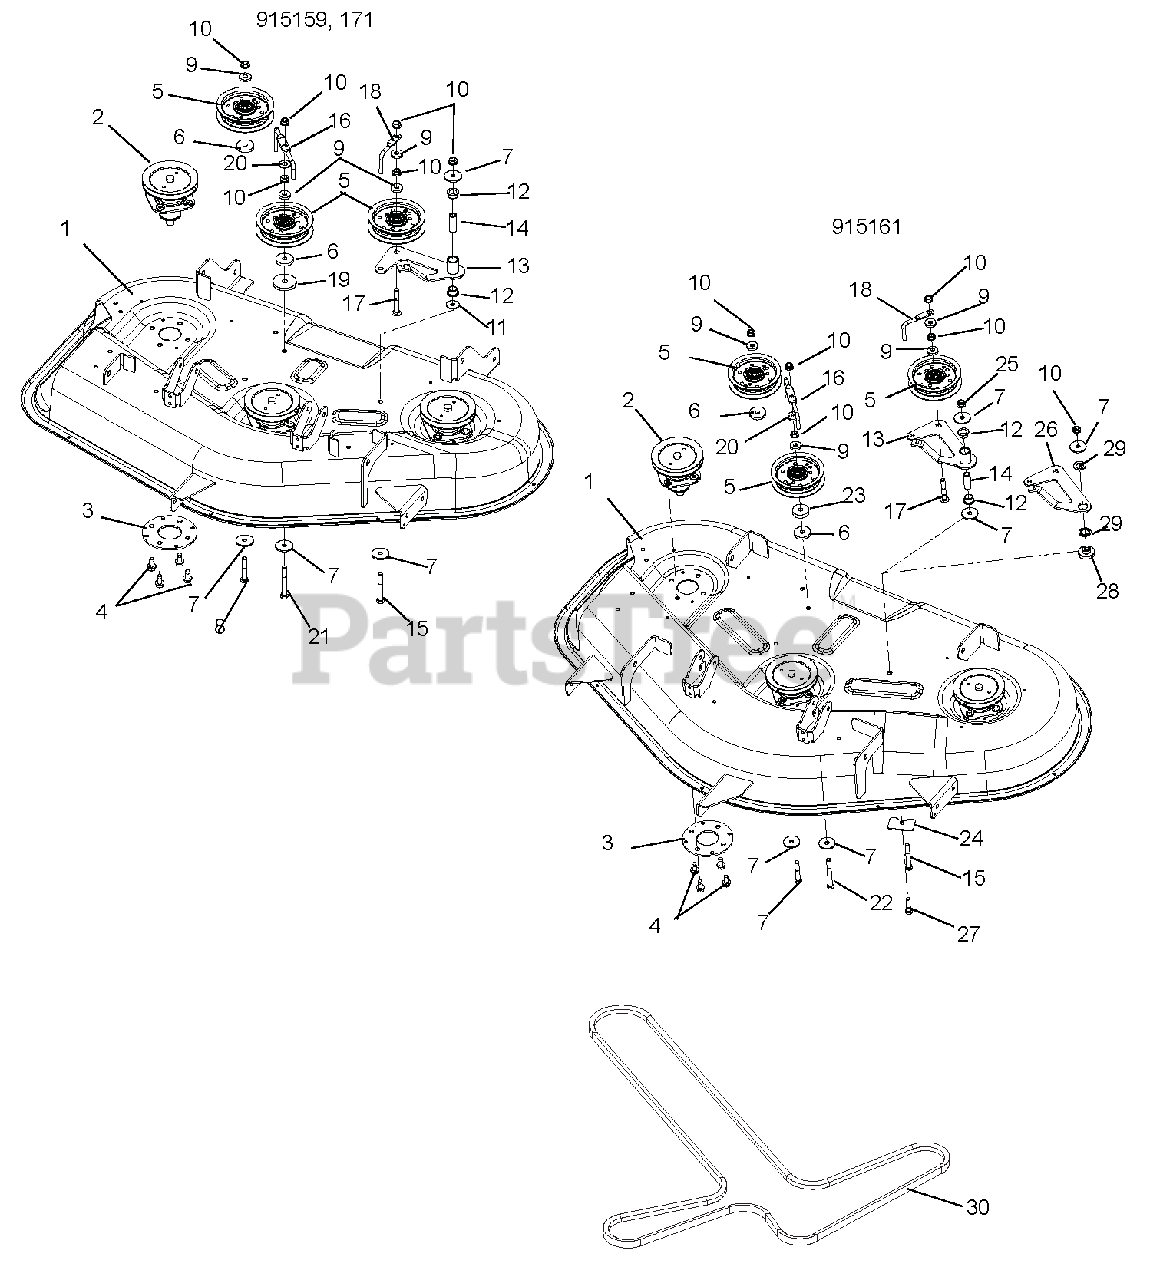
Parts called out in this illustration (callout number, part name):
1	WMT, 42" ZOOM DECK
1	WMT, 50 DECK STAMPED
2	KIT, DECK SPINDLE ASM (42)
2	KIT, DECK SPINDLE ASM (34/50)
3	PLATE-REINF, SPINDLE
4	@SCR-TAP .38-16X.75 HWH TR YWZ
5	ASM, IDLER 4"
6	WSHR,FLT STL.406X1.50X.245YWZC
7	WSHR-FL-STL .380X1.50X.125YWZC
8	@BLT-HEX .38-16X2.25 GR5 YWZC
9	WSHR-FL-STL .406X1.00X.188 YWZ
10	@NUT-LK-TOP-FLG .38-16 YWZC
11	WSHR-FL-STL .375X1.125X.065YWZ
12	BSHG-FLG, .625X.750X.500X1.00
13	WMT, IDLER ARM
14	SPACER, .375IDX.625ODX1.66 PM
15	@BLT-HEX .38-16X2.75 GR5 YWZC
16	WIREFORM, BELT FINGER
17	@BLT-RDHDSQNK .38-16X2.50 G5YZ
18	WIREFORM, BELT FINGER
19	WSHR-FL-STL .469X2.00X.25 YWZC
20	@WSHR-FL-STL.438X1.00X.083 YWZ
21	@BLT-HEX .38-16X3.00 GR5 YWZC
22	@BLT-HEX .38-16X3.25 GR5 YWZC
23	SPACER, .39 X 1.50 X .380
24	PLATE-DECK REINF.
25	@NUT-LK-NYL-FLG .38-16 YWZC
26	IDLER ARM
27	@BLT-HEX .38-16X1.50 GR5 YWZC
28	SPACER, IDLER ARM
29	BUSHING, IDLER ARM
30	V-BELT, 4L-WRAPPED
